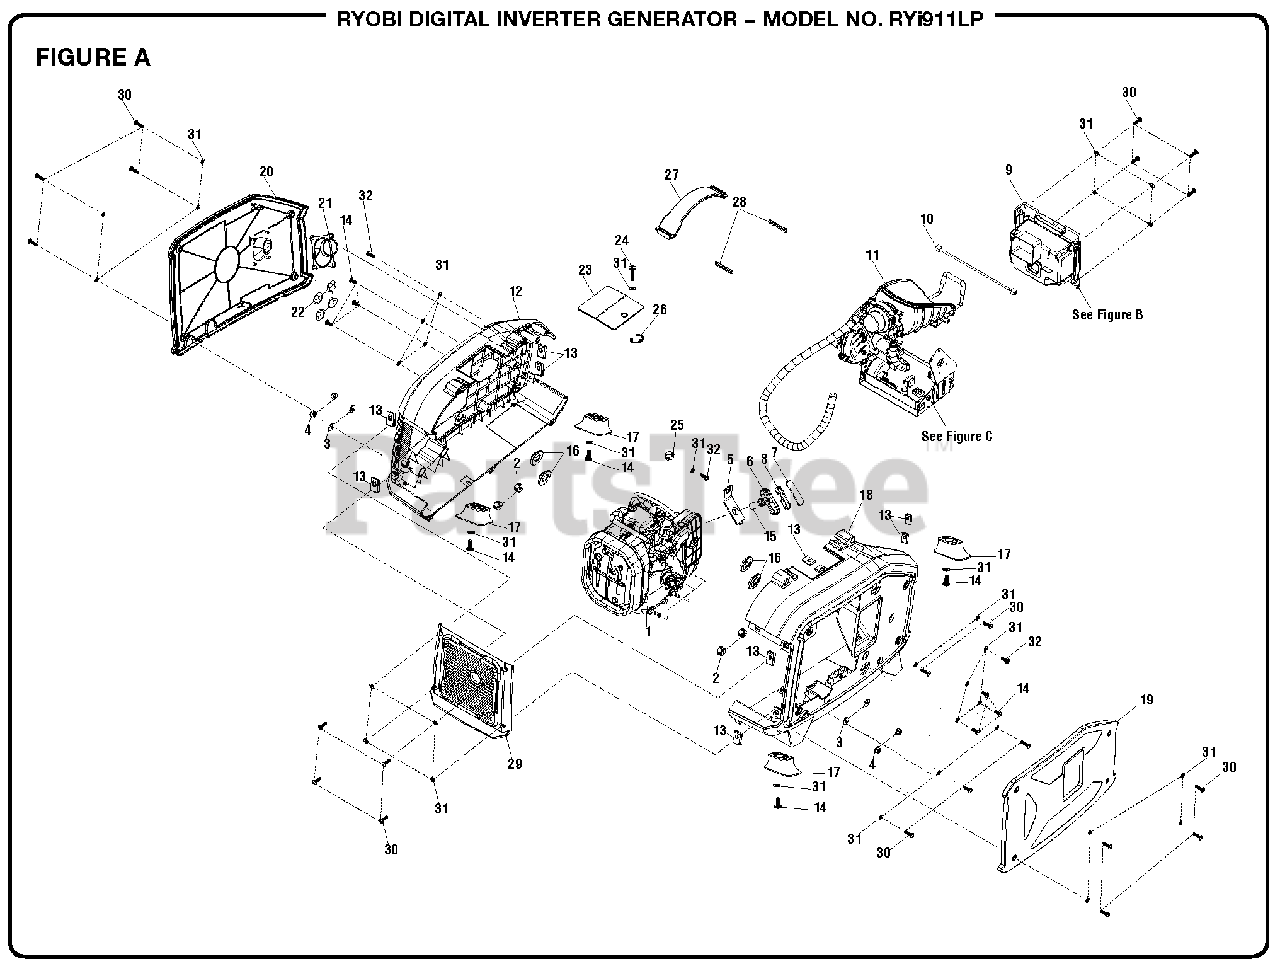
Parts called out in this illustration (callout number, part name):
1	Engine
2	Side Engine Isolator
3	Rubber Washer (ID6.25 x OD15.5 x 2t)
4	Lock Flange Nut (M6)
5	Starter Cover
6	Recoil Handle
7	Recoil Handle Cover
8	Recoil Handle Support
9	Control Panel Assembly
10	Stepper Motor Extended Wire Harness
11	Fuel System & Bracket Assembly
12	Panel Housing (Right)
14	Screw (M5 x 12 mm, T-25 Torx Pan Hd.)
15	Rubber Grommet Handle
16	Rubber Grommet
17	Rubber Foot w/Metal Insert and Ribs
18	Panel Housing (Left)
19	Maintenance Panel (Left)
20	Maintenance Panel (Right)
21	Rubber Grommet
22	Internal Tooth Washer (ID5)
23	Spark Plug Door
24	Screw (M5 x 16 mm, T-25 Torx Pan Hd.)
25	Fuel Hose Clamp
26	E-Clip Lock Washer
27	Rubber Handle (Upper)
28	Side Lock (U-Shaped)
29	Muffler Cover
30	Screw (M5 x 18 mm, T-25 Torx Pan Hd.)
31	Washer (ID5.2 x OD10 x 1t)
32	Screw (M5 x 16 mm, T-25 Torx Pan Hd.)
